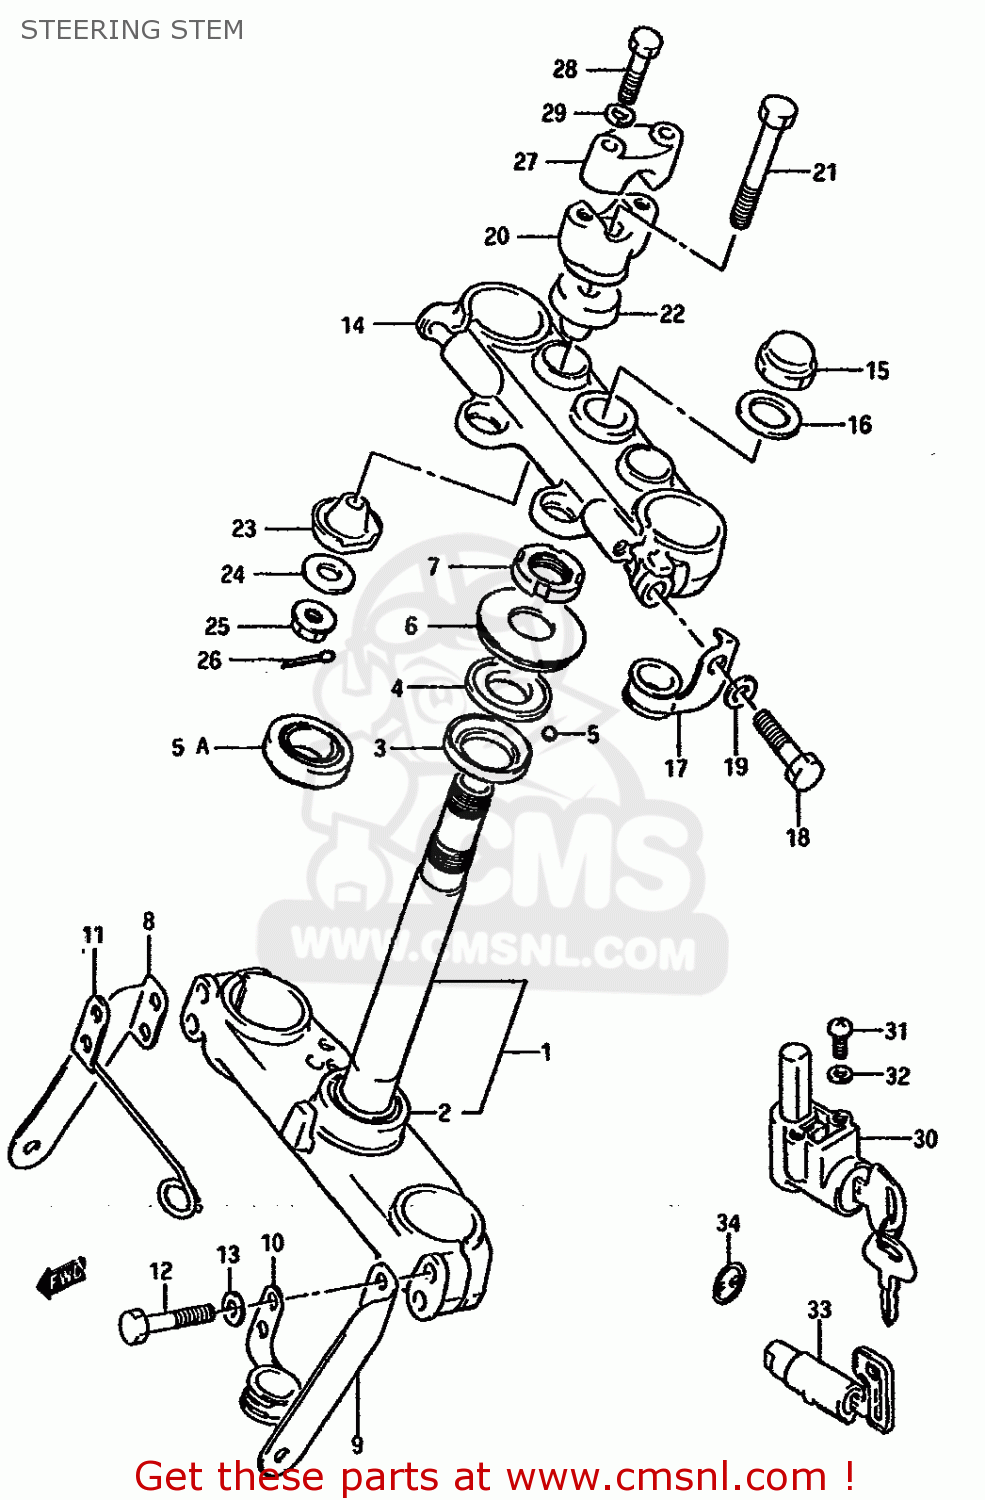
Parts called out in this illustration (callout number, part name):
1	STEM,STEERING
2	BEARING
3	RACE,STEERING INNER (SUJ)
4	RACE,STEERING,OUTER,UPPER
5	BALL
5A	TAPER,ROLLER BEARING
6	SEAL,STEERING UPR DUST
7	NUT,STEERING STEM
8	BRACKET,FRONT SIDE RH
9	BRACKET,FRONT SIDE LH
10	CLIP,LH LOWER
11	GUIDE, SPEEDOMETER CABLE
12	BOLT
13	LOCK WASHER
14	BRACKET,UPPER
15	NUT
16	WASHER
17	CLIP,UPPER LH
18	BOLT
19	LOCK WASHER
20	HOLDER,HANDLE LWR
21	BOLT,HANDLE HOLDER
22	DAMPER,UPR
23	DAMPER RUBBER,LOWER
24	WASHER
25	NUT
26	COTTER PIN
27	HOLDER,HANDLE UPR
28	BOLT
29	WASHER,LOCK,8.
30	LOCK ASSY,STEERING
31	SCREW
32	LOCK WASHER
33	LOCK ASSY,STEERING(NEIMAN)
34	LABEL,STEERING LOCK
